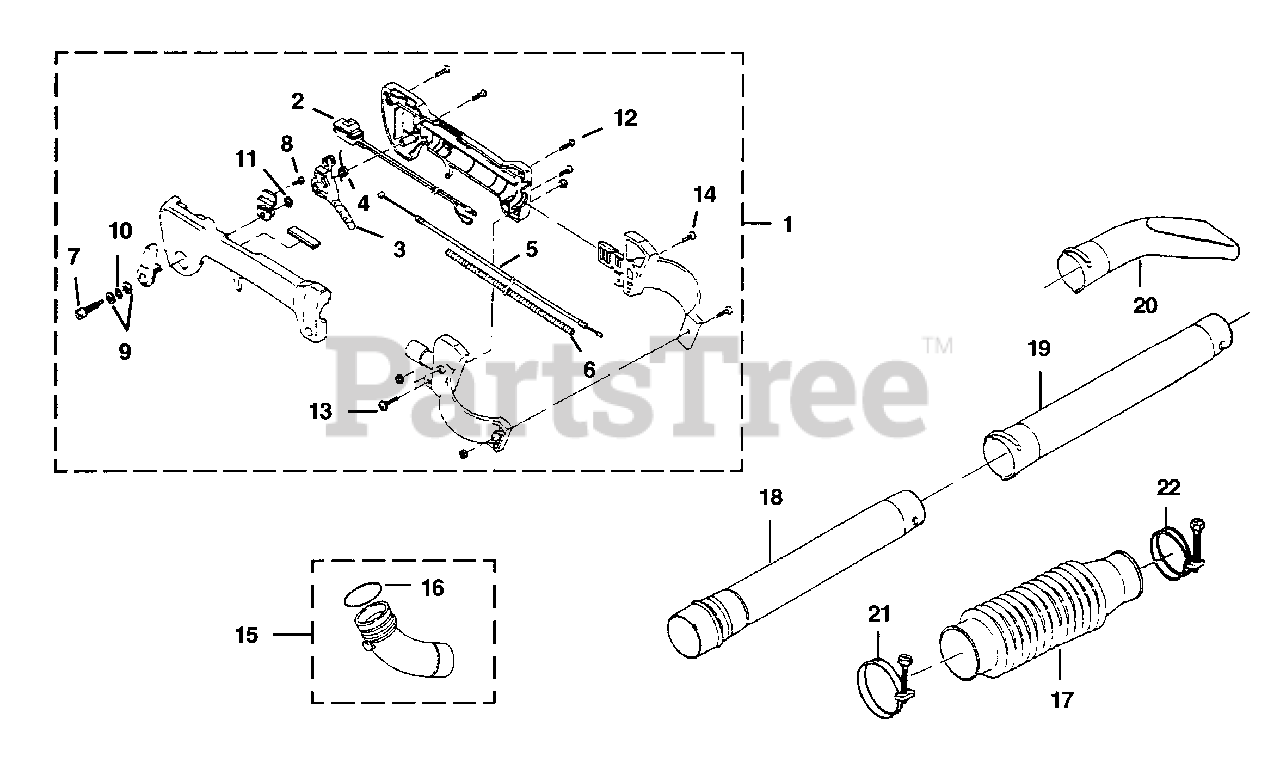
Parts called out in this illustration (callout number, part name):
1	CONTROL LEVER ASSEMBLY
2	SWITCH COMPLETE
3	TRIGGER-Throttle
5	CABLE-Throttle
6	SPIRAL CABLE TUBE
7	SCREW-Socket Hd (M6 x 30)
8	SCREW-Self Tapping (M4 x 8)
10	WASHER-Wave
11	NUT (M6)
12	SCREW-Self Tapping (M4 x 16)
13	SCREW ASSEMBLY (M5 x 25 W SW)
14	SCREW-Pan Hd (MS x 20)
15	ELBOW COMPLETE
17	TUBE-Flexible
18	TUBE-Upper
19	TUBE-Lower
21	CLAMP-Hose
22	CLAMP-Hose
